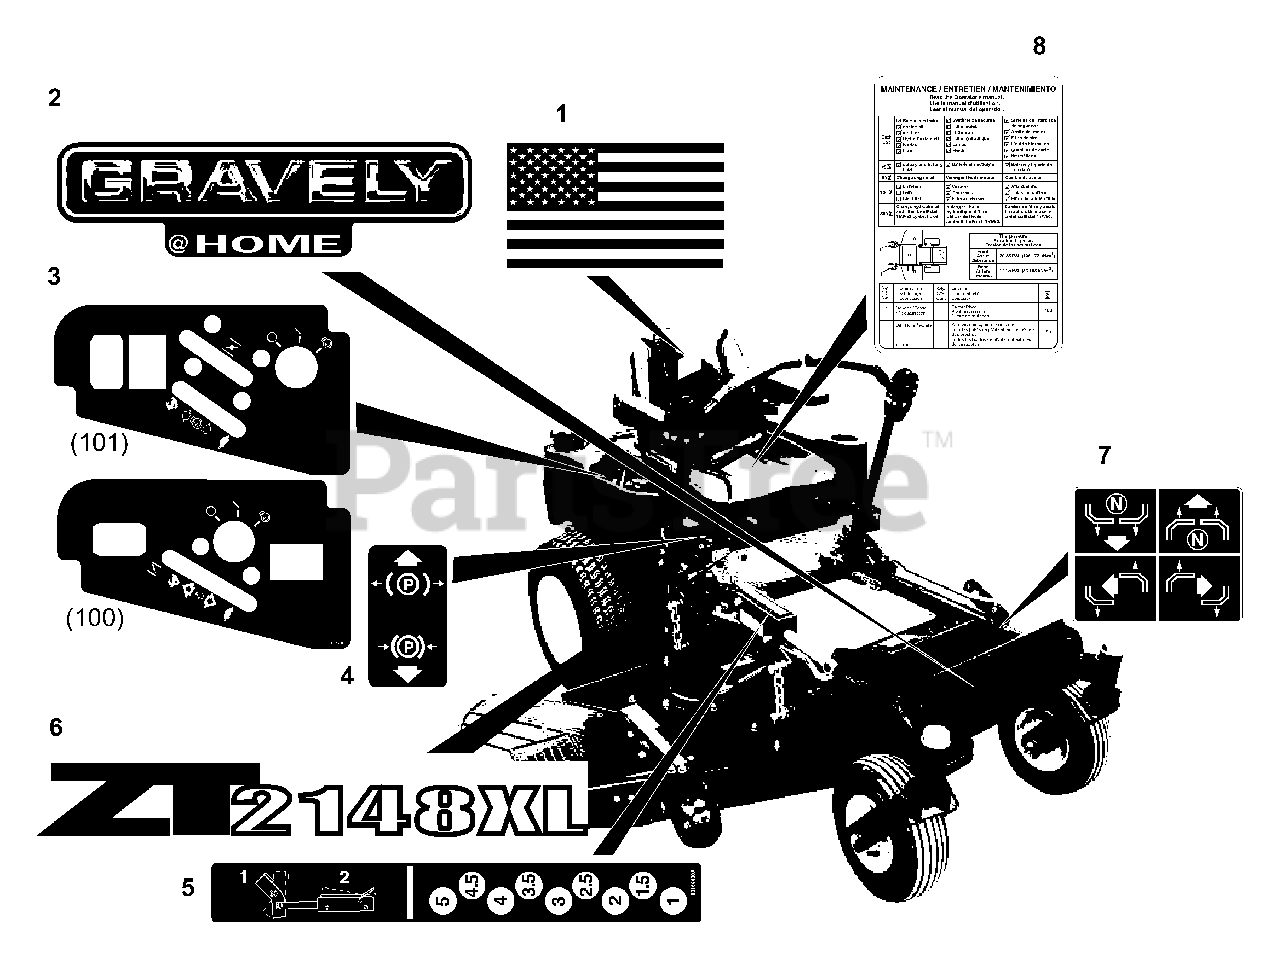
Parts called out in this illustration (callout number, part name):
1	Decal, American Flag
2	Decal, Gravely @ Home
3	Decal, Control Panel (101)
3	Decal, Control Panel (100)
4	Decal, Parking Brake Lever
5	Decal, Height of Cut
6	Decal, ZT 2148XL (101)
6	Decal, ZT 1844XL (100)
7	Decal, Instructional Steering
8	Decal, Service Instructions
